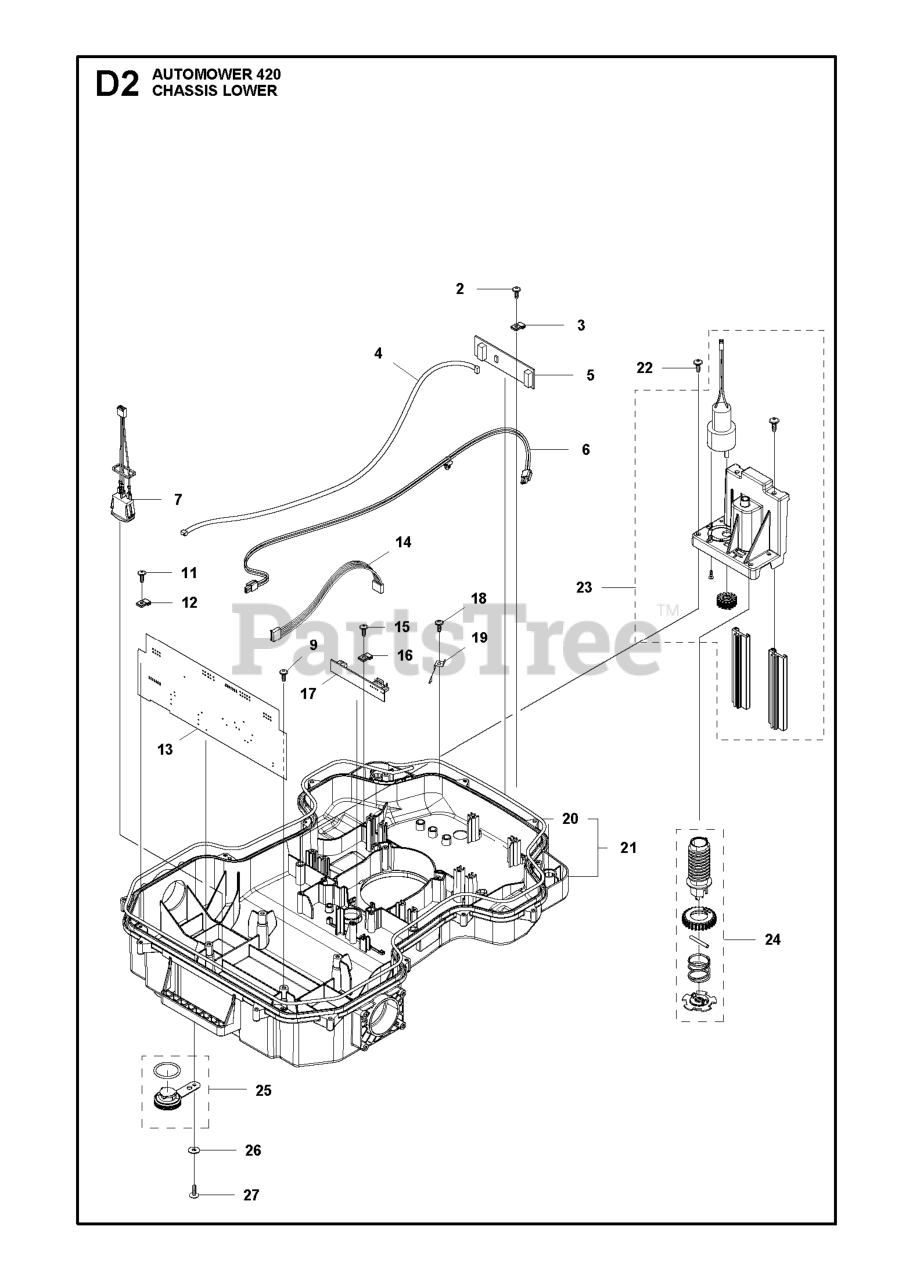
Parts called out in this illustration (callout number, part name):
1	BATTERY LI-ION
2	SCREW 14MM
3	CLAMP PCB
4	LOOM LOOP SENSOR
5	PRINTED CIRCUIT ASSY LOOP SENS
6	LOOM CHARGING LINK HIGH CHARGI
7	LOOM ON/ OFF
8	HOLDER BATTERY
9	SCREW ITXPANT
10	HOLDER TWIST LOCK
11	SCREW 14MM
12	CLAMP PCB
13	PRINTED CIRCUIT ASSY PCBA MAIN
14	LOOM HEIGHT ADJUSTMENT
15	SCREW 14MM
16	CLAMP PCB
17	PRINTED CIRCUIT ASSY PCBA CUTT
18	SCREW 14MM
19	SPRING GUIDE HEIGHT ADJUSTMENT
20	SEALING STRIP
22	SCREW 14MM
23	MOTOR ASSY HEIGHT MOTOR
24	SCREW KIT
25	PLUG KIT
26	WASHER
27	SCREW ITXPANT
